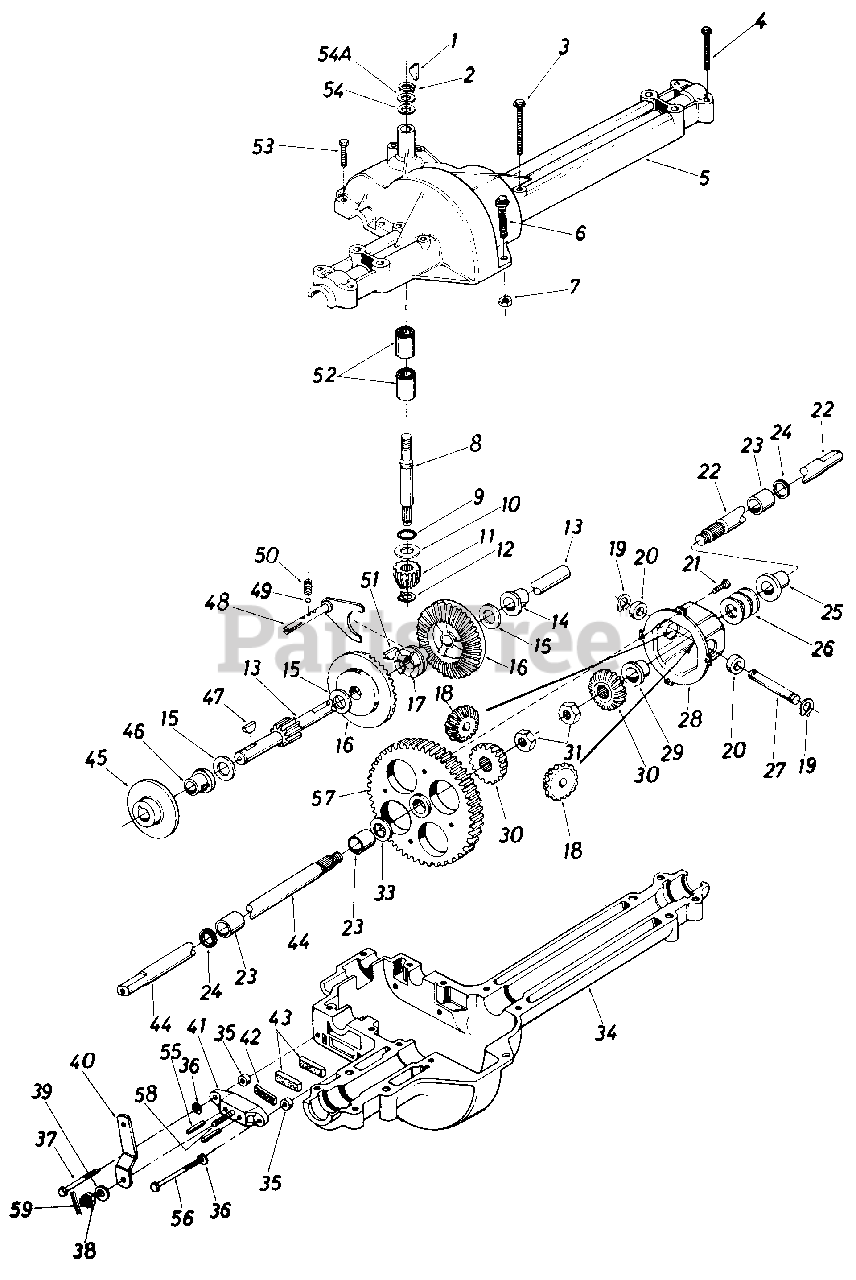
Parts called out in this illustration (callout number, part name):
1	#4 Hi-Pro Key 3/32 x 5/8" Dia.
2	Snap Ring .625" Shaft
3	Hex Bolt 1/4-20 x 1.75" Lg.*
4	Hex Bolt 1/4-20 x 1.25" Lg.*
5	Upper Housing
6	Hex Fl-Bolt 1/4-20 x .88" Lg.*
7	Hex Nut 1/4-20 Thd.*
8	Input Shaft
9	Square Seal 5/8" I.D.
10	Thrust Washer 5/8" I.D. x 1.25" O.D.
11	Pinion Input 14T
12	Retaining Ring 7/16" Ext.
14	Flange Brg. 5/8" I.D. x 3/4" Lg.*
15	Fl-Wash.
16	Bevel Gear 42T
17	Clutch Collar
18	Miter Gear 1 5T
19	Snap Ring
20	Thrust Bearing 1/2" I.D. x 1.0" O.D.
21	Pan Head Scr. 1/4-20 x .50" Lg. w/ Patch
22	Axle R.H. Kit
23	Sleeve Bearing 3/4" I.D. x 1.0" L5
24	Oil Seal 3/4" I.D.
25	Flange Bearing 3/4" I.D. x 15/16" Lg.
26	Fl-Wash. .760" I.D. x 1.49" O.D.
27	Cross Shaft
28	Differential Housing Ass'y.
31	Retaining Ring
33	Fl-Wash. .760" I.D. x 1.49" O.D.
34	Lower Housing
35	Spacer .53" O.D. x 3/8" Lg.
36	L-Wash. 1/4" I.D.
37	Hex Bolt 1/4-20 x 1.50" Lg. (Grade 5)
38	Castle Nut 5/16-24 Thd.
39	Fl-Wash. .344" I.D. x .875" O.D.
40	Actuating Arm
42	Puck Plate
43	Brake Puck
44	Axle L.H. Kit
46	Flange Bearing 5/8" I.D. x 15/16" Lg.
47	Woodruff Key 3/16 x 5/8 HT
48	Shift Fork Ass'y.
49	Ball Detent.250" Dia.
50	Spring Detent
51	#9 Hi-Pro Key 3/16 x 3/4" Dia. HT
52	Needle Brg. 5/8" I.D. x 1/2" Lg.
53	Hex Bolt 1/4-20 x 1.00" Lg.
54	Fl-Wash. 5/8" I.D. x .030
54A	Fl-Wash. 5/8" I.D. x .040
55	Actuating Pin 5/16" Dia.
56	Hex Bolt 1/4-20 x 1.50" Lg. (Grade 5)
57	Differential Gear 72T Ass'y. w/ Bearing
58	Sq. Hd. Bolt 5/16-24 Thd.
59	Cotter Pin 3/32" Dia. x .50" Lg.
